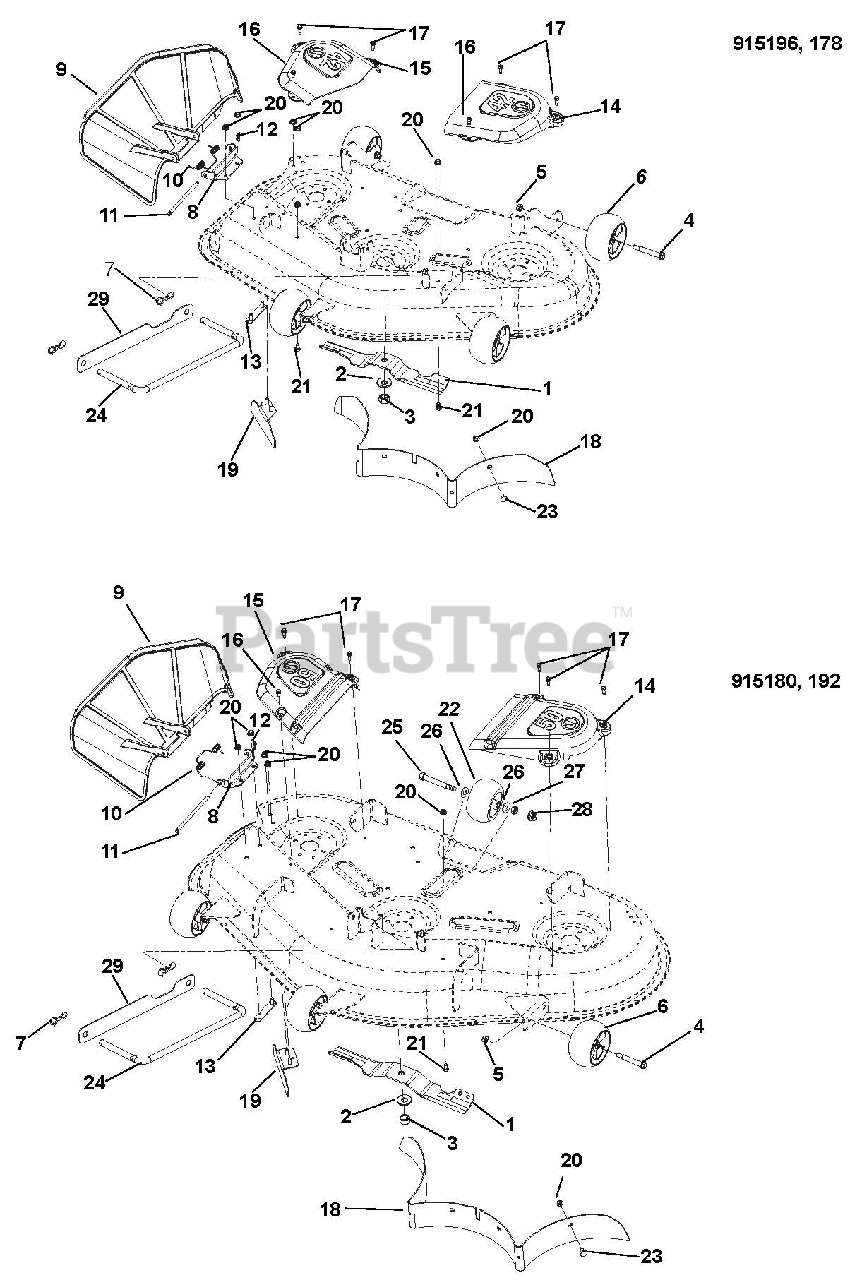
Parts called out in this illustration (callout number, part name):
1	Mower Blade, 14.83"
1	Blade, Mower 17.35"
2	Washer, Bellville .63 x 1.625 x .14
3	Nut, Hex .62-18
4	Bolt, Shoulder .38-16 x 2.50 Hex Washer Head
5	Nut, Locking Top Flange .38-16
6	Anti-Scalp Wheel, 5 x 3 OS
7	Pin, Bow Tie Locking Cotter .091 x 1.875
8	Bracket, Discharge Chute Mount 42"
8	Bracket, Discharge Chute Mount 50"
9	Discharge Chute – Molded
10	Spring, Torsion
11	Pin, 5/16 x 5.80"
12	Pin, Hair Internal .08 x .18 x 1.18
13	Weldment, Discharge Chute MT. Strap
14	Belt Cover, Left Hand 42"
14	Belt Cover, Left Hand 50"
15	Belt Cover, Right Hand 42"
15	Belt Cover, Right Hand 50"
16	Screw, Tapping .25-20 x .50 Hex Washer Head
17	Screw, Tapping .25-20 x .75 Hex Washer Head
18	Baffle, 42 Rear
18	Baffle, 50 Rear
19	Weldment – Baffle, Discharge 42"
19	Baffle, 50" Deflector
20	Nut, Locking Top Flange .31-18
21	Bolt, Hex .31-18 x .50
22	Roller
23	Bolt, Round Head Square Neck .31-18 x .75
24	Wireform, Drag Link
25	Bolt, Hex .38-16 x 3.50
26	Washer, Flat Steel .406 x .812 x .065
27	Nut, Locking Center Jam .375-16
28	Nut, Locking Nylon Flange .38-16
29	Strap, Drag Link
